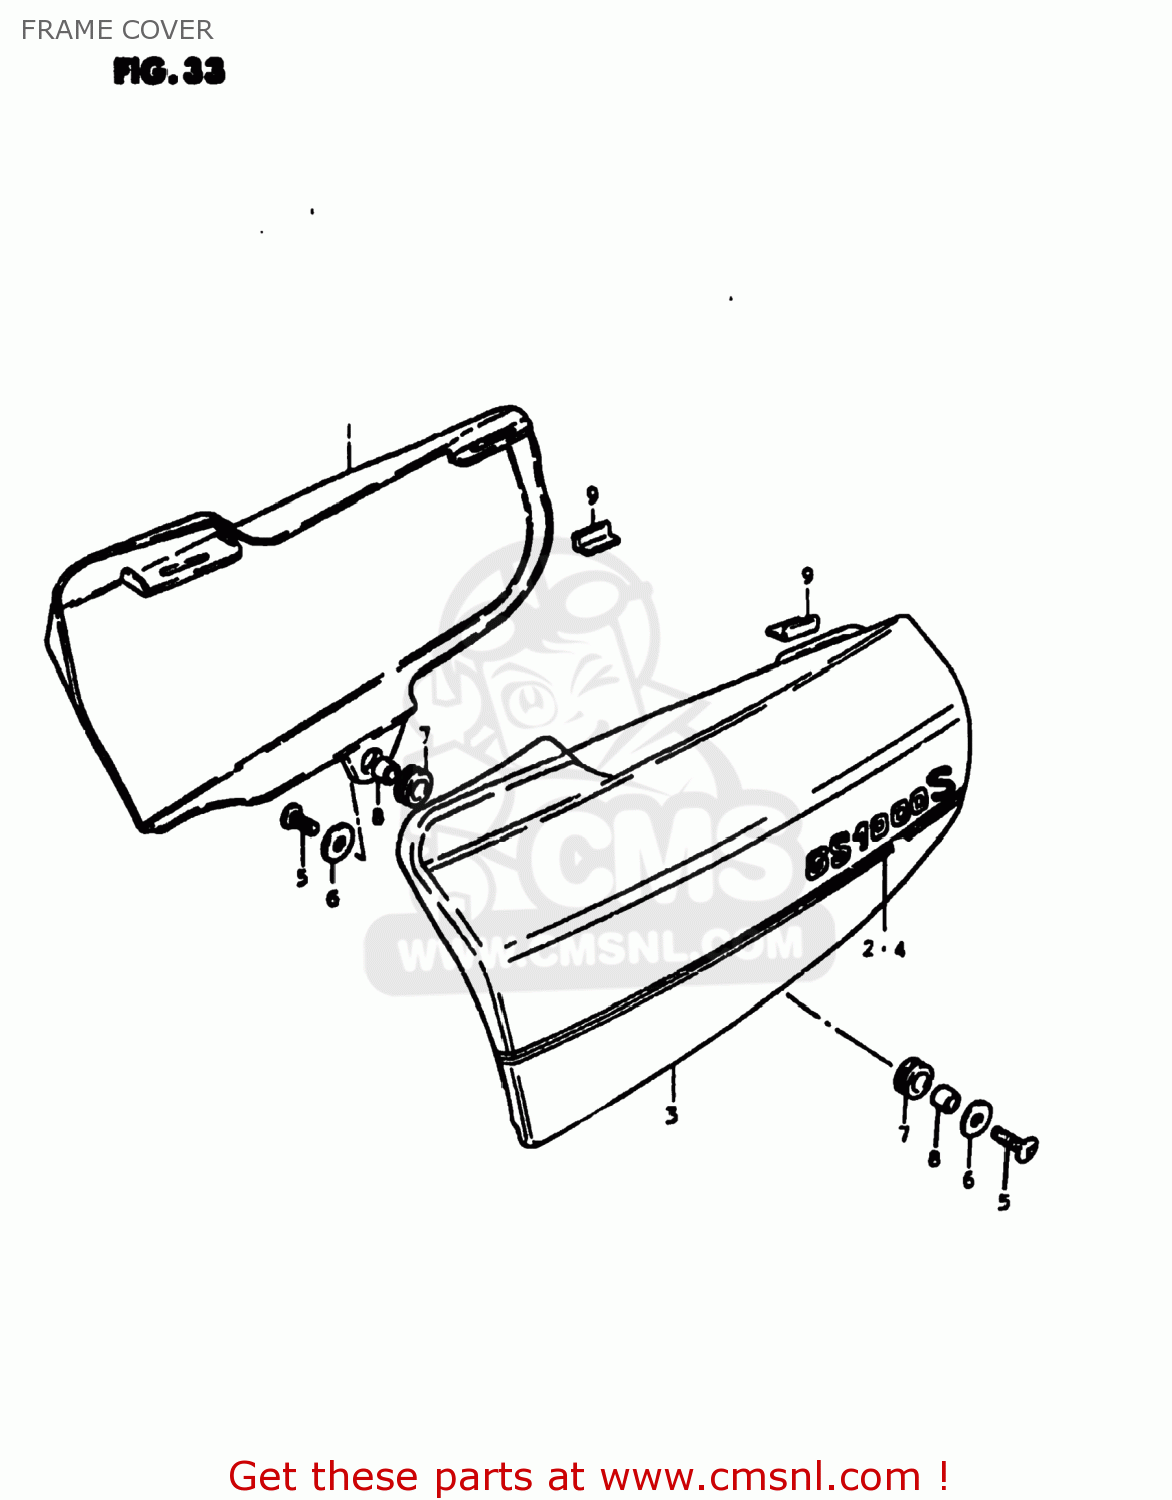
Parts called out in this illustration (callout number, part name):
1	COVER,FRAME,RIGHT
2	TAPE,FRAME COVER
3	COVER,FRAME,LEFT
4	TAPE,FRAME COVER
5	SCREW
6	WASHER (6.5X18X1.6)
7	CUSHION
8	SPACER (6.8X10X10)
9	CUSHION,FRAME COVER
